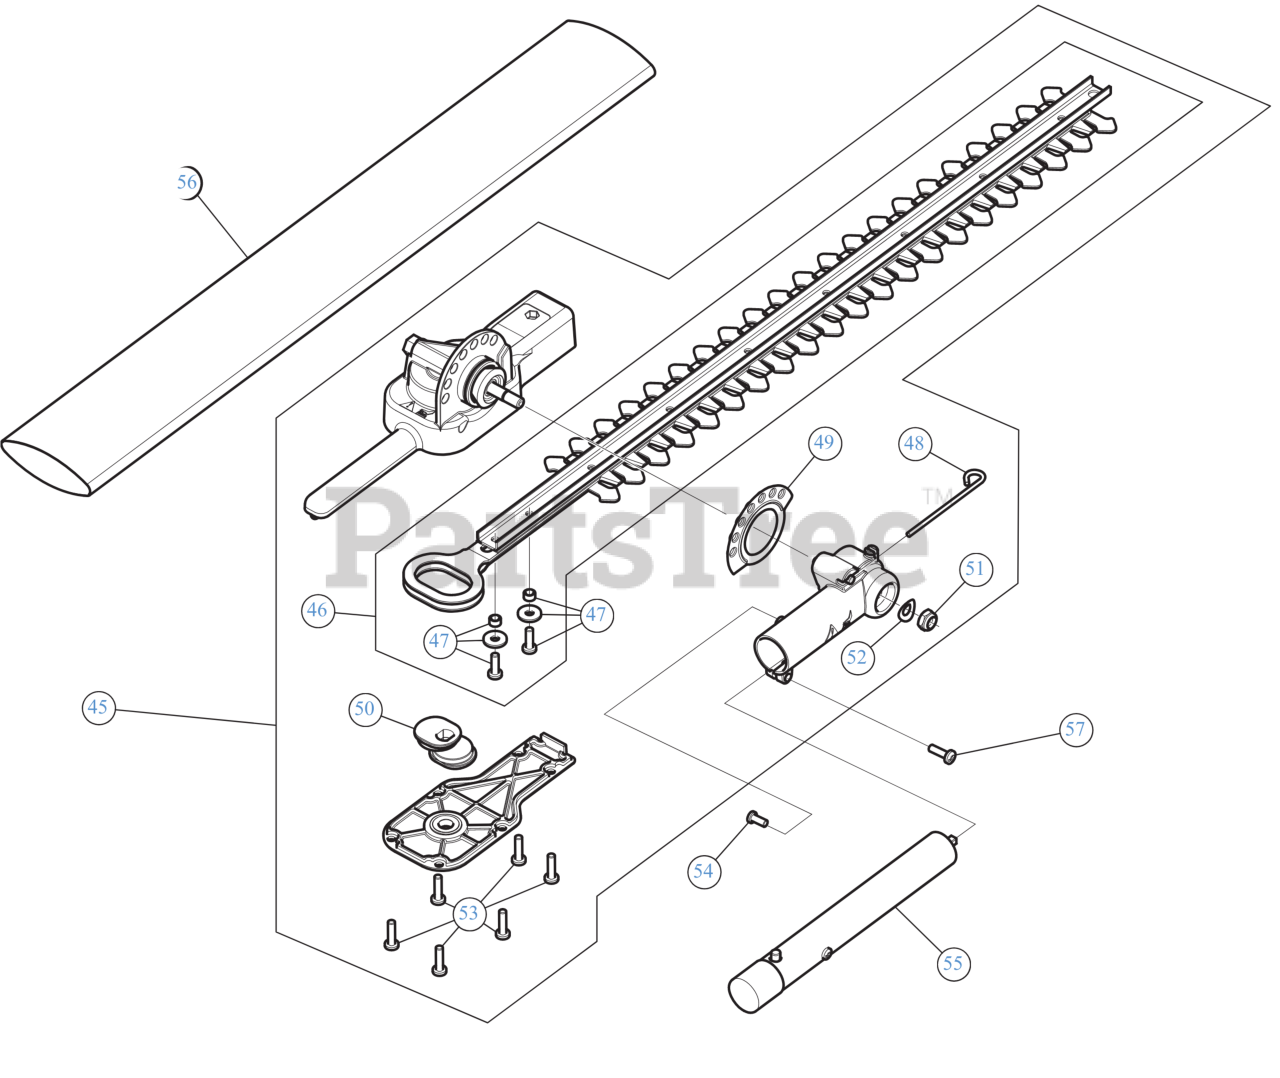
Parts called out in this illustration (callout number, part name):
45	GEARBOX ASSEMBLY
46	BLADE ASSEMBLY
47	BLADE HARDWARE
48	LOCKING LEVER PIN
49	SPACER DETENT SHM
51	HEX NUT
52	SHAKE PROOF WASHER
53	SCREW - 10-24X.625 PAN HEAD
54	SCREW 8-32X.437
55	BOOM ASSEMBLY
56	BLADE COVER
57	SCR, M5 x 15.8MM
